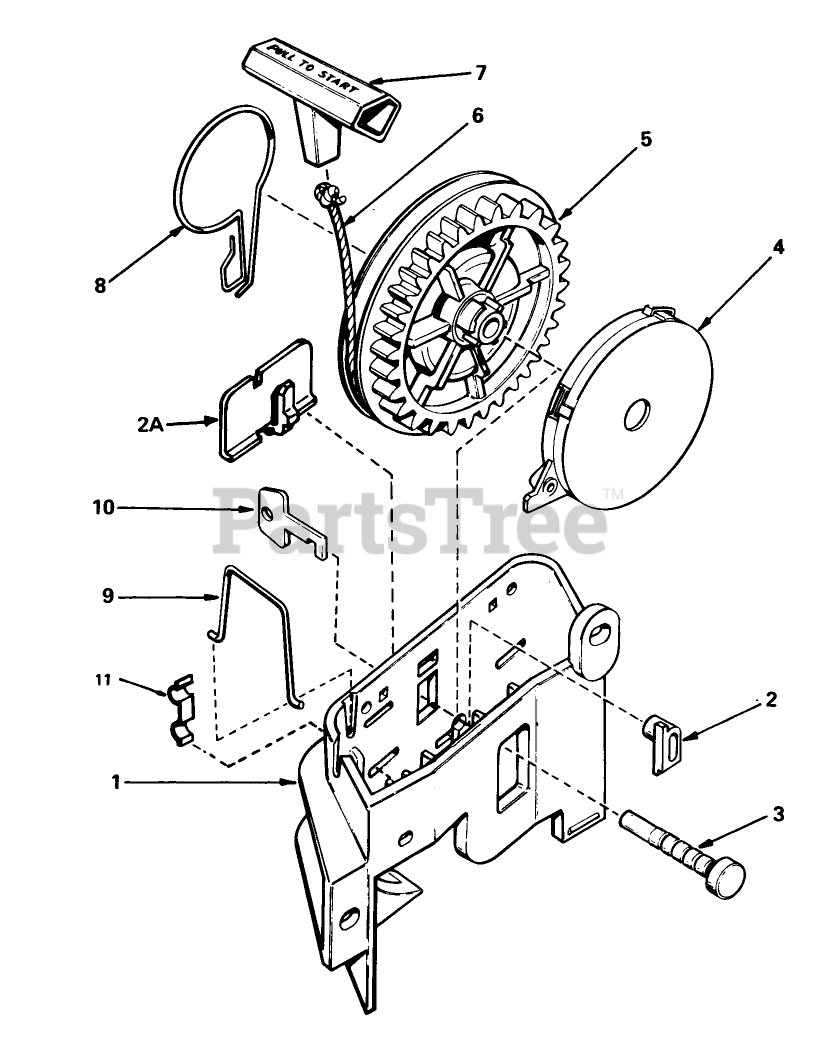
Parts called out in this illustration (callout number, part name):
1	Bracket Starter
2	Pawl, Locking Not used on all engine models)
2A	Clip, Starter Bracket (Used On Starters Not Equipped With Pawl, Ref. No. 2)
3	Pin-Pulley
4	Spring Assy., Rewind (Incl. #3)
6	Rope Starter (Length 65" & 9/64" Dia.)
7	Handle-Starter
9	Clip-Rope
10	Key (Not Used On All Engine Models
11	Washer-Thrust
